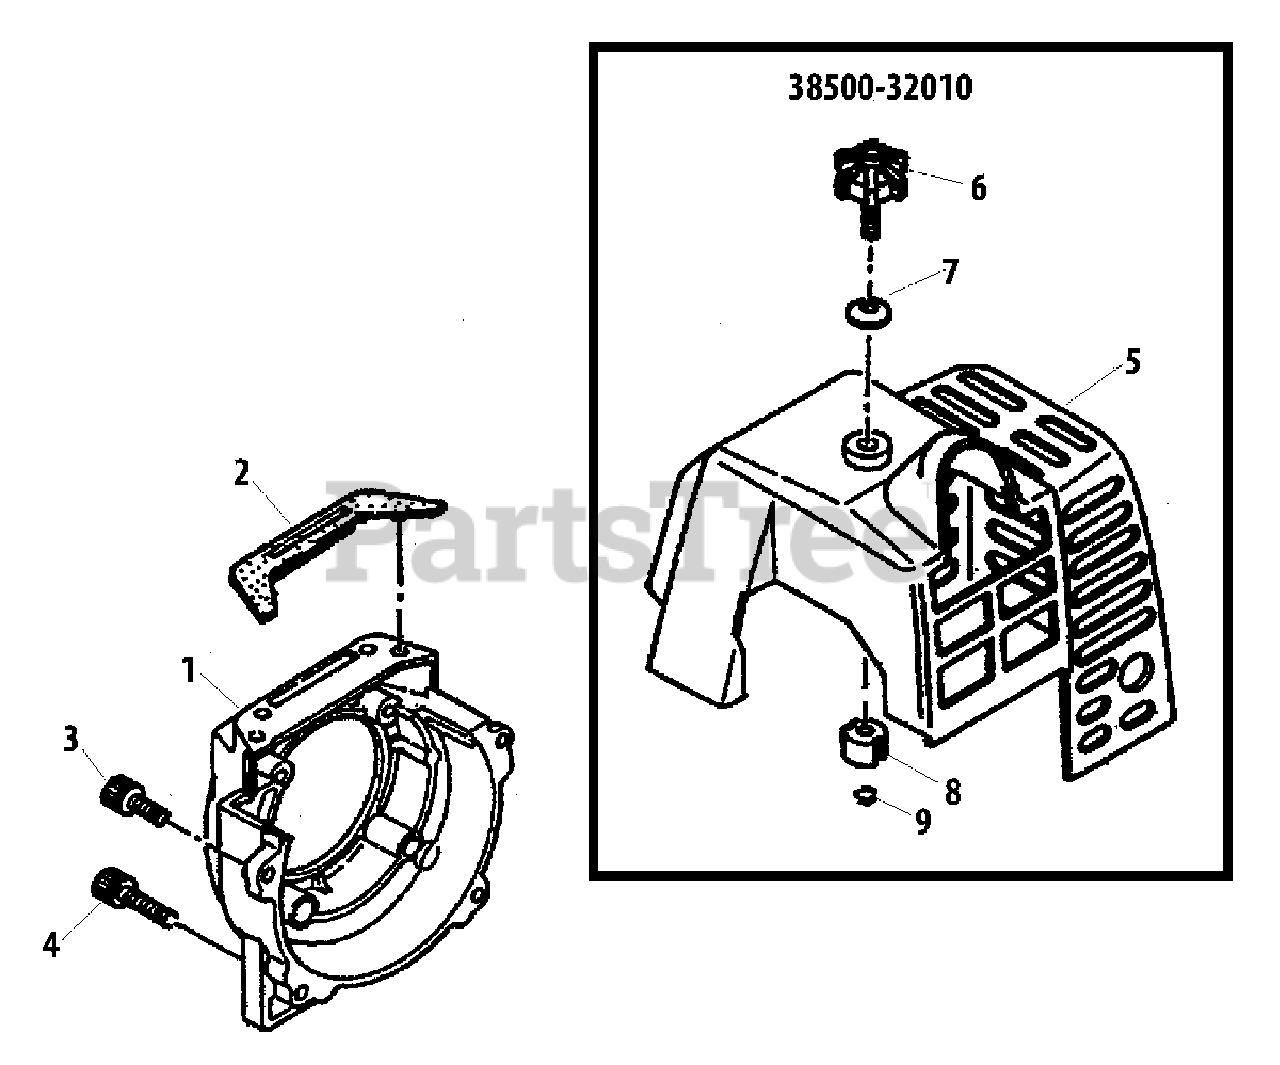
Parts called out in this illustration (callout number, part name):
1	COVER, FAN
3	SCREW - 5X16
4	SCREW - 5X35
5	COVER, ENGINE
6	THUMBSCREW
7	WASHER - CONICAL
8	INSULATOR
9	CLIP
38500-32010	ENGINE COVER KIT
